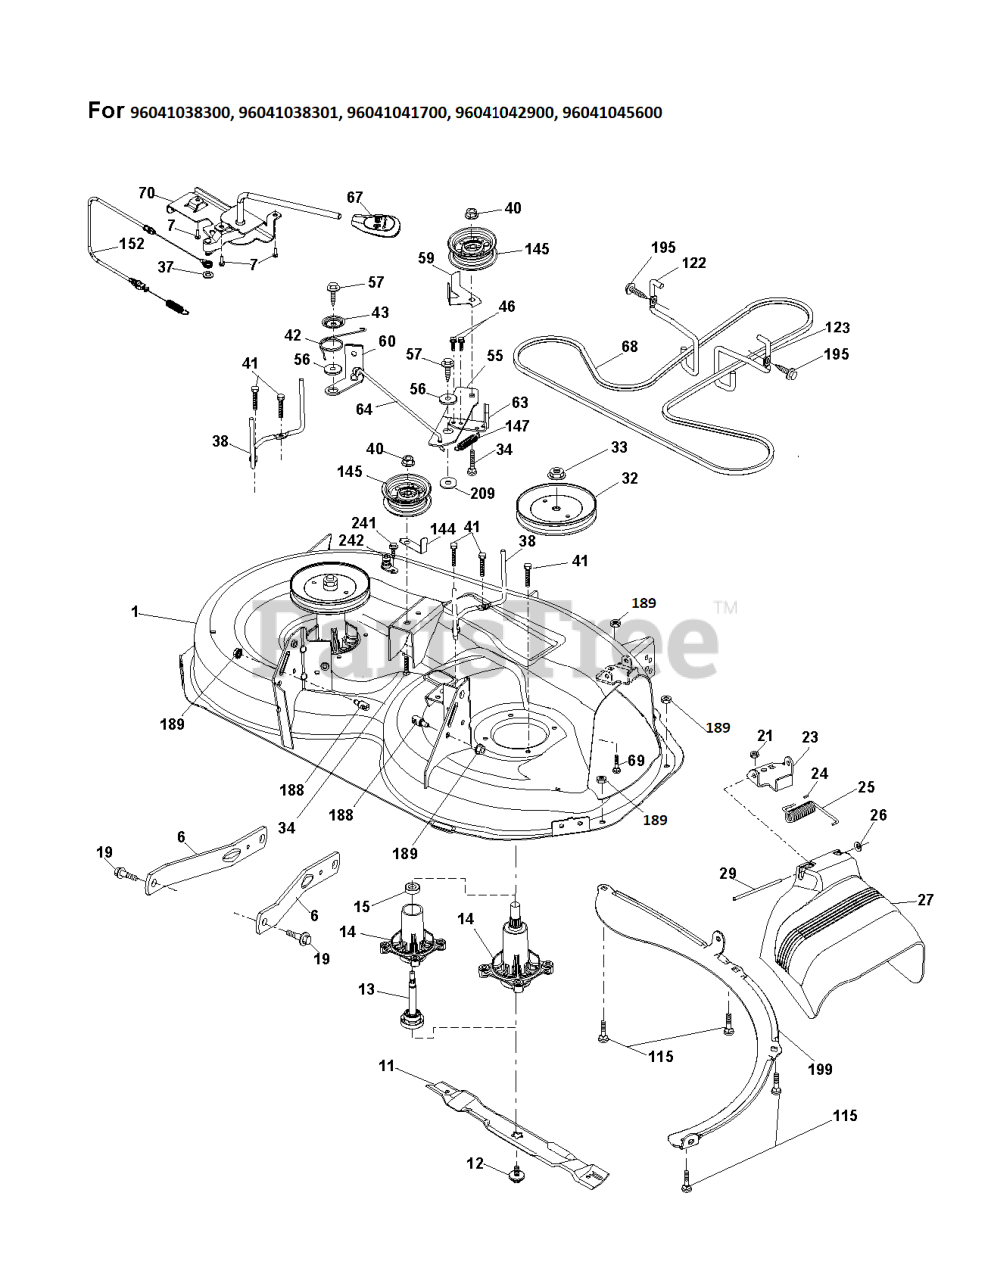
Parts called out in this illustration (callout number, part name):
1	DECK SVCX1.38"194251X418 KIT
6	SERVICE.KIT ARM.SUSPENSION.MOW
11	BLADE.2 IN 1.38"DECK.BLACK
12	SCREW.SEMS.7/16-20X1.HEX.HEAD
13	KIT.MANDREL.NONGREASE.TALL
14	KIT.MANDREL.NONGREASE.TALL
15	BEARING.MANDREL.TOP.EXTENDED
19	BOLT.SHOULDER
23	BRKT.DEFLECTOR.38"2005+
24	CAP-SLEEVE LT
25	SPRING.TORSION.DEFLECT
26	NUT PUSH M
27	SHIELD.DEFLECTOR.MOWER.38"
32	SERVICE KIT PULLEY PULLEY.MAND
34	GSPW Bolts
37	WASHER PLAIN WASHER 3/8 X 0.08
38	BELT KEEPER.MANDREL.38"COATED
40	NUT.HEX.FLANGE.3/8-16.LOCKNUT
41	BOLT.HEX.WASHR.HED.313-18X1.19
42	SPRING.TORSION.BRAKE
43	SRPING.TORSION.RETAINE
46	SCREW.1/4-20X5/8
55	SERVICE KIT IDLER.ARM
56	SPACER.RETAINER
57	SCREW 3/8-16X1
59	SERVICE KIT GUARD
60	ARM BRAKE MOWER RH 38"
63	BRAKE.ARM.LH.38"TEX.COATED
64	LINKAGE.BRAKE.ASM.ZINC
67	HANDLE.CLUTCH.CABLE.LT
70	CLUTCH.ASM.MANUAL.LT.PRED
115	BOLT ROUND HEAD SQUARE NECK BO
122	SERVICE KIT BELT KEEPER
123	SERVICE KIT KEEPER BELT KEEPER
144	SERVICE.KIT KEEPER BELT KEEPER
145	PULLEY.IDLER.FLAT
147	SPRING RETURN
152	CABLE.CLUTCH.MANUAL.
188	STUD.W/"D"ANTI-ROTATION
195	SCREW, 3/8-16X3/4
199	SERVICE KIT BAFFLE BAFFLE.VORT
241	SCREW.TT.#10-32X.5.3/8.FLANGE
242	PORT.WASHOUT
